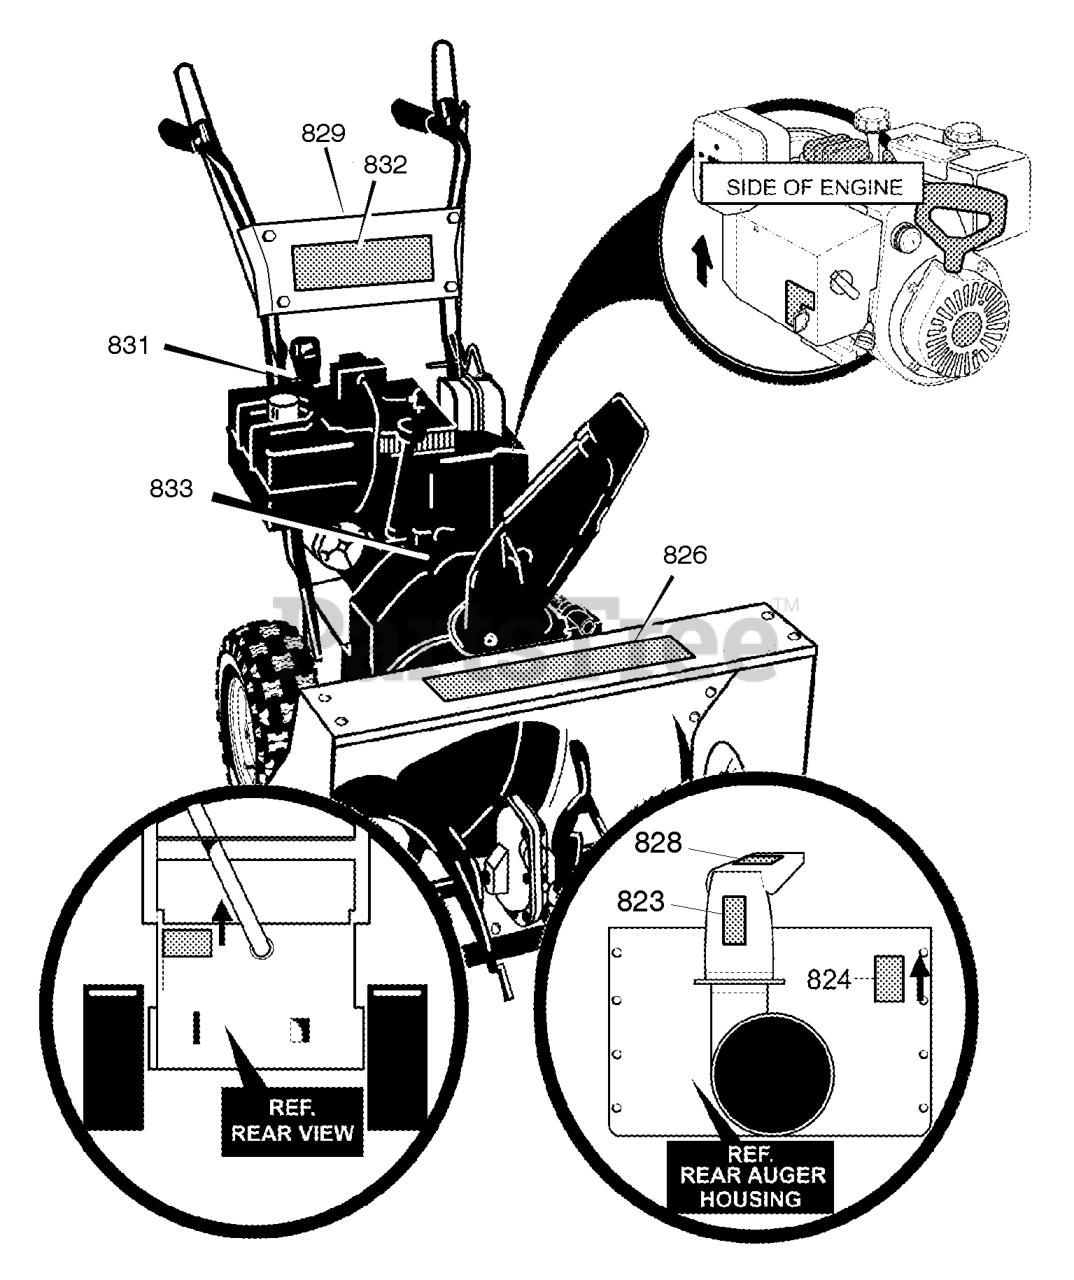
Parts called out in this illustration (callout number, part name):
823	DECAL, DANGER CHUTE HAND
824	DECAL, DANGER FOOT
826	DECAL, CRAFTSMAN 9/27
828	DECAL, THROWN OBJECTS
829	DECAL, DRIVE CLUTCH / AUGER
831	DECAL, GEAR SELECTOR
832	DECAL, CRAFTSMAN
833	DECAL, LID, TOOL BOX
